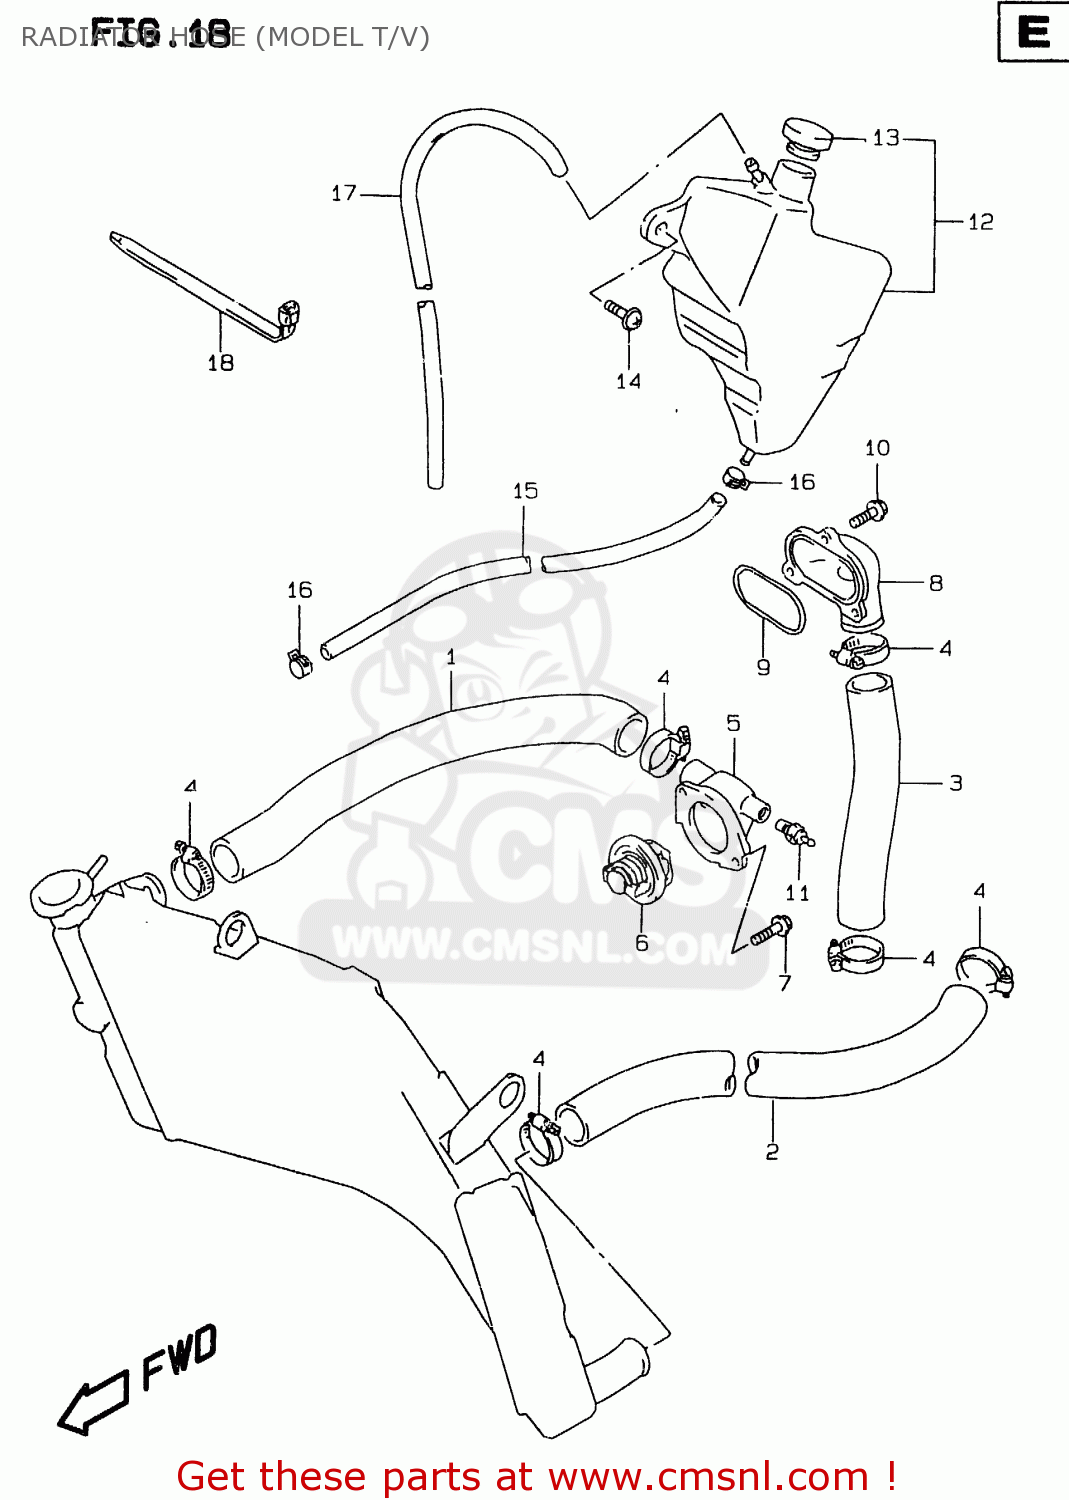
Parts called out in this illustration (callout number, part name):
1	HOSE,RADIATOR INLET
2	HOSE,RADIATOR OUTLET
3	HOSE,CYLINDER INLET
4	CLAMP
5	CONNECTOR,THERMOSTAT INLET
6	THERMOSTAT,WATER
7	BOLT
8	CONNECTOR,CYLINDER WATER,INTAKE
9	O RING,CYL WATER CONNECTOR
10	BOLT
11	GAUGE ASSY,WATER TEMP
12	TANK ASSY,RESERVOIR
13	CAP,RESERVOIR TANK
14	SCREW(6X20)
15	HOSE,RESERVOIR TANK INLET
16	CLIP
17	HOSE,RESERVOIR TANK OUTLET
18	CLAMP L:165
